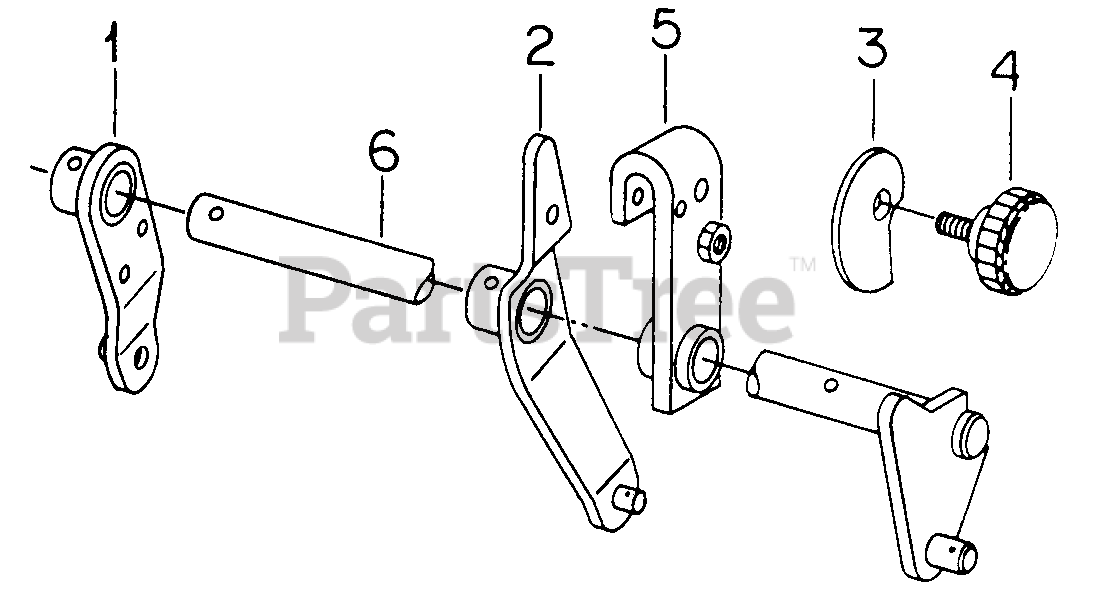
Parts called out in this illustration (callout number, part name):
1	Arm Assy, Lift, LH
2	Arm Assy, Lift, RH
4	Knob, Torque
5	Bracket Assy, Lift
6	Rockshaft Assy
